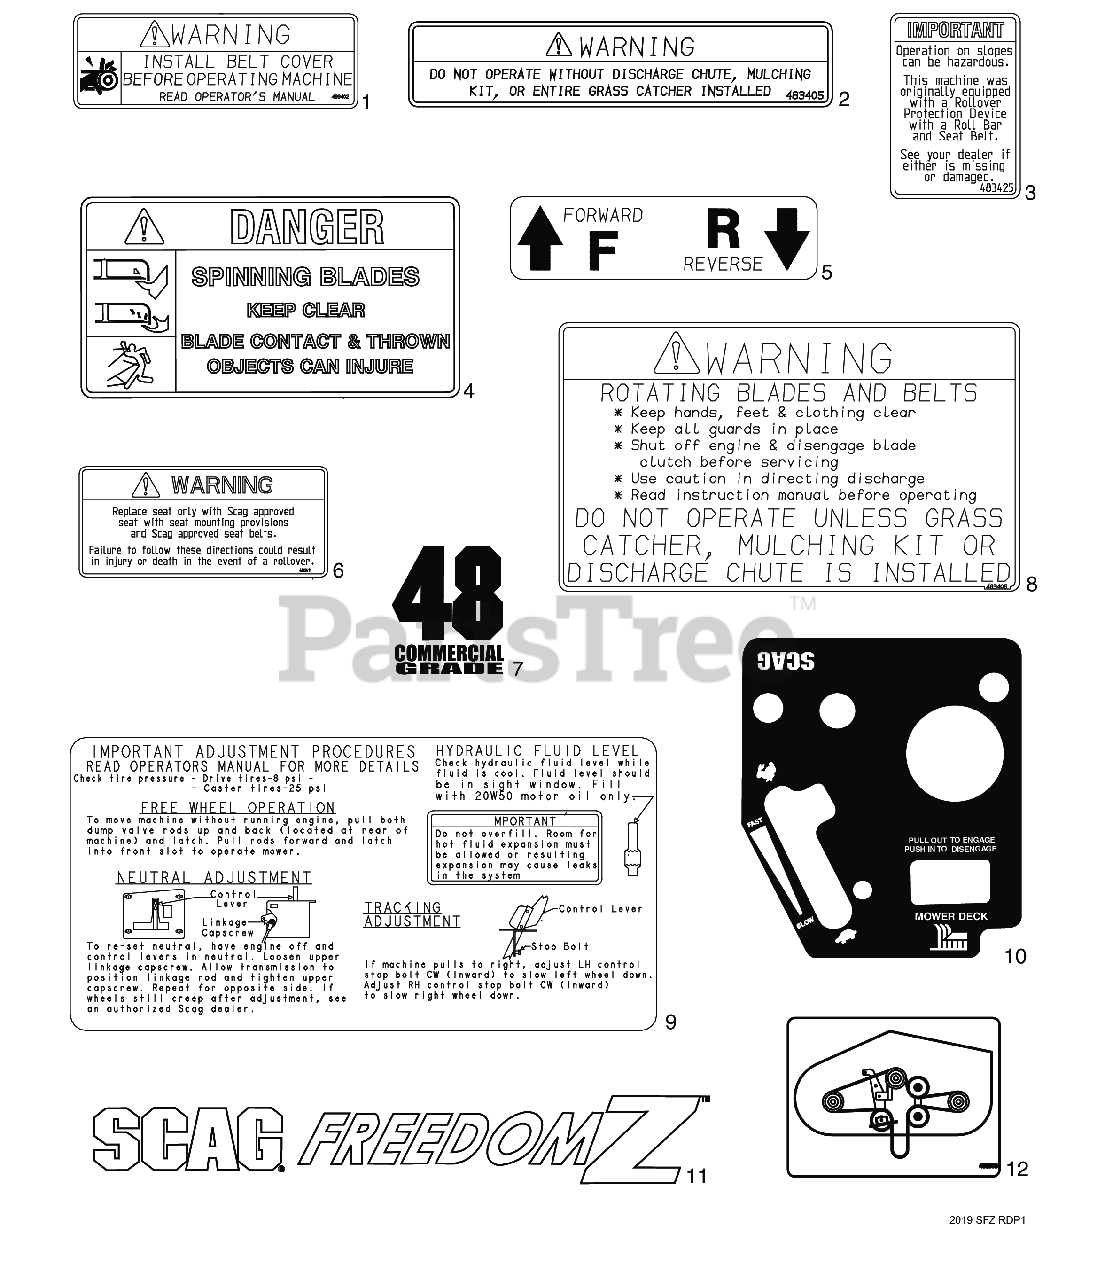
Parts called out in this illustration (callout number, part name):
1	Decal, Warning - Belt Cover
2	Decal, Warning-Discharge
3	Decal, ROPS
4	Decal, Spinning Blades
5	Decal, Traction Control
6	Decal, Seat Replacement
7	Decal, 48 Commercial
7	Decal, 52 Commercial
8	Decal, Warning - Rotating Blades
9	Decal, Adjustment SFZ
10	Decal, Instrument Panel - SFZ48, SFZ52 & SFZ 61
11	Decal, Front SFZ
12	Decal, SZL / SFZ / SPZ Belt Routing
